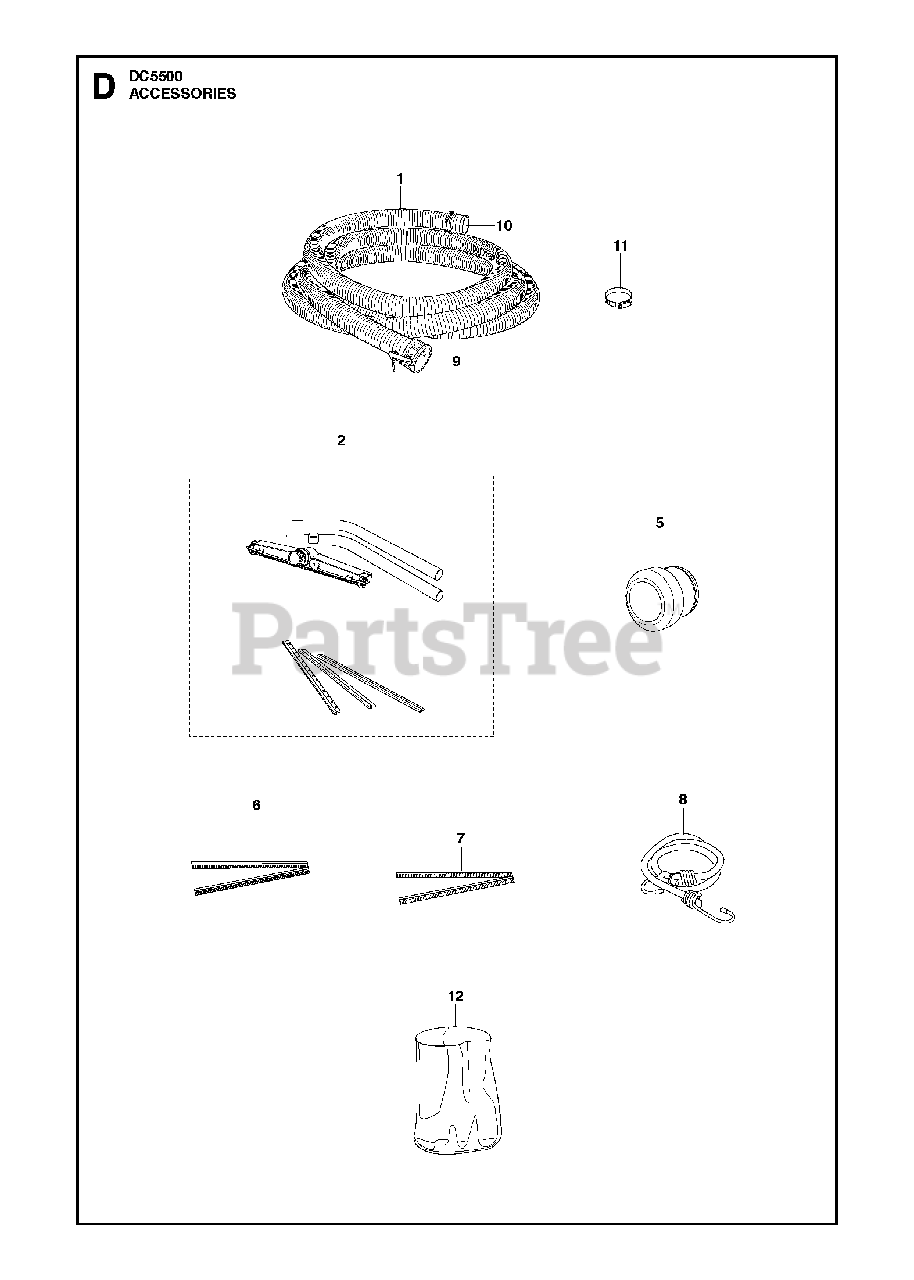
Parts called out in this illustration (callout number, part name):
5	ADAPTERDiam 38mm, Valid to 2013-10
5	ADAPTERDiam 42mm, Valid from 2013-10 and forward
12	BAGSINCLUDES 200 ITEMS
